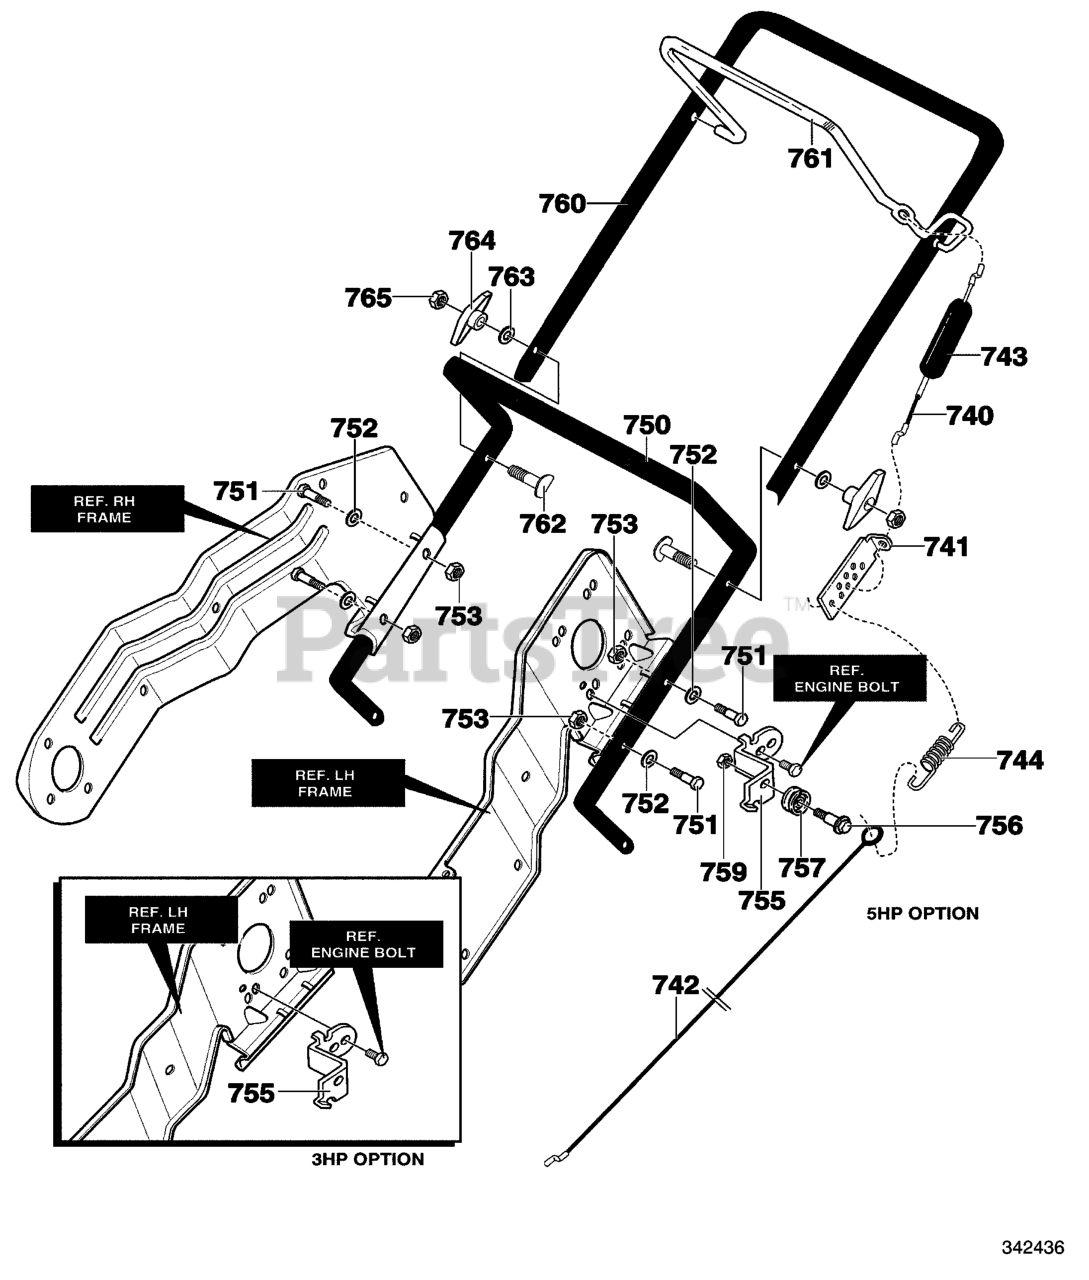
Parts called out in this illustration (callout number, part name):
740	CABLE, UPPER
741	BRKT, CABLE ADJ
742	CABLE LOWER CONTROL
743	BOOT, CLUTCH SPRING
750	HANDLE LOWER
751	SCREW, 1/4-20X1.25
752	WASHER, FLAT .281X.63X.065
753	NUT, 1/4-20
755	BRACKET, CABLE
756	BOLT, .375X.375 1/4-20
757	PULLEY, .906X.305
759	NUT, 1/4-20
760	HANDLE, UPPER
761	BAIL, CONTROL
762	BOLT, 5/16-18X2.00
763	WASHER, FORM
764	KNOB,T
765	NUT, 5/16-18
